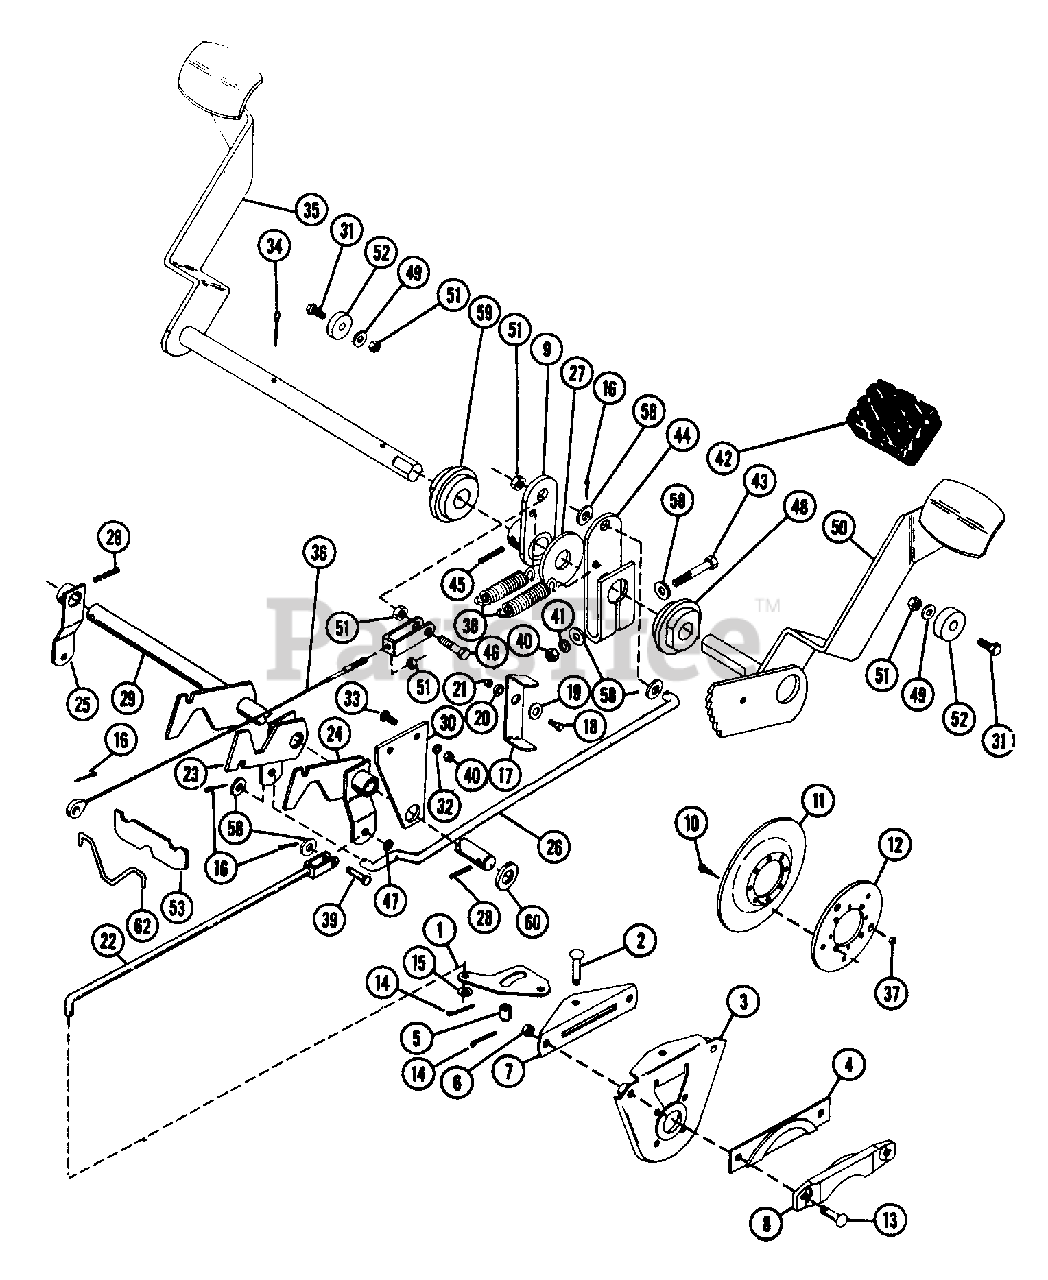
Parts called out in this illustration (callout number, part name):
1	BRAKE ARM
2	PIN-CLEV .371X1.62 YWZC
3	PLATE, CALIPER MOUNTING
4	FRICTION PLATE
6	NUT-LK-NYL .375-16 PL
7	PRESSURE PLATE
8	CALIPER PLATE
9	CLUTCH LEVER
10	BLT-SERHFWH .25-20X.50 PL
12	CARRIER
13	BLT-RDHDSQNK .38-16X3.50 GR5PL
14	PIN-COTR .09X.75 PL
15	WSHR-FL-STL .323X.625X.062 PL
16	PIN-COTR .12X.75 PL
17	BRAKE LATCH
18	BLT-HEX .25-20X.75 PL GR2
19	WSHR-FL-STL.281X.62X.065 PL
20	SPACER BUSHING .37 X .26 X .14
21	NUT-LK-CTR .250-20 PL
22	BRAKE ROD
23	BRAKE ARM
25	BRAKE ARM
26	BRAKE ROD
27	WSHR-FL-STL .755X1.375X.062 PL
28	PIN-GRV .250X1.25 TP A
29	BRAKE SHAFT
31	BLT-HEX .31-18X.88 PL GR2
32	WSHR-LK .375X.115 HVY PL
33	BLT-RDHDSQSHNK .38-16X1.00 PL
34	PIN-COTR .18X1.25 PL
35	L H PEDAL 14G
35	L H PEDAL 10G
36	CLUTCH CABLE
37	GROMMET
38	SG-TENS .090X.75X3.50 WLD 34
39	PIN-CLEV .373X1.12 YWZC
40	NUT-HEX .375-16
41	WSHR-LK .375X.094 MED PL
42	PEDAL PAD
43	BLT-HEX .38-16X2.25 GR2
44	ARM-BRAKE
45	PIN-ROLL .188X1.25
46	BLT-HEX .31-18X1.50 PL GR5
47	GROMMET
48	BSHG-FLG .750X1.750X.875X2.125
49	WSHR-FL-STL .38X.875X.083 PL
50	R. H. LEVER
51	NUT-LK .312-18 GR A PL
52	SPACER .344X1.000X.375
53	BALANCE LINK
58	WSHR-FL-STL.406X.812X.065PL
59	BSHG-FLG .750X1.750X.875X2.125
60	WSHR-FL-STL .754X1.125X.062 PL
